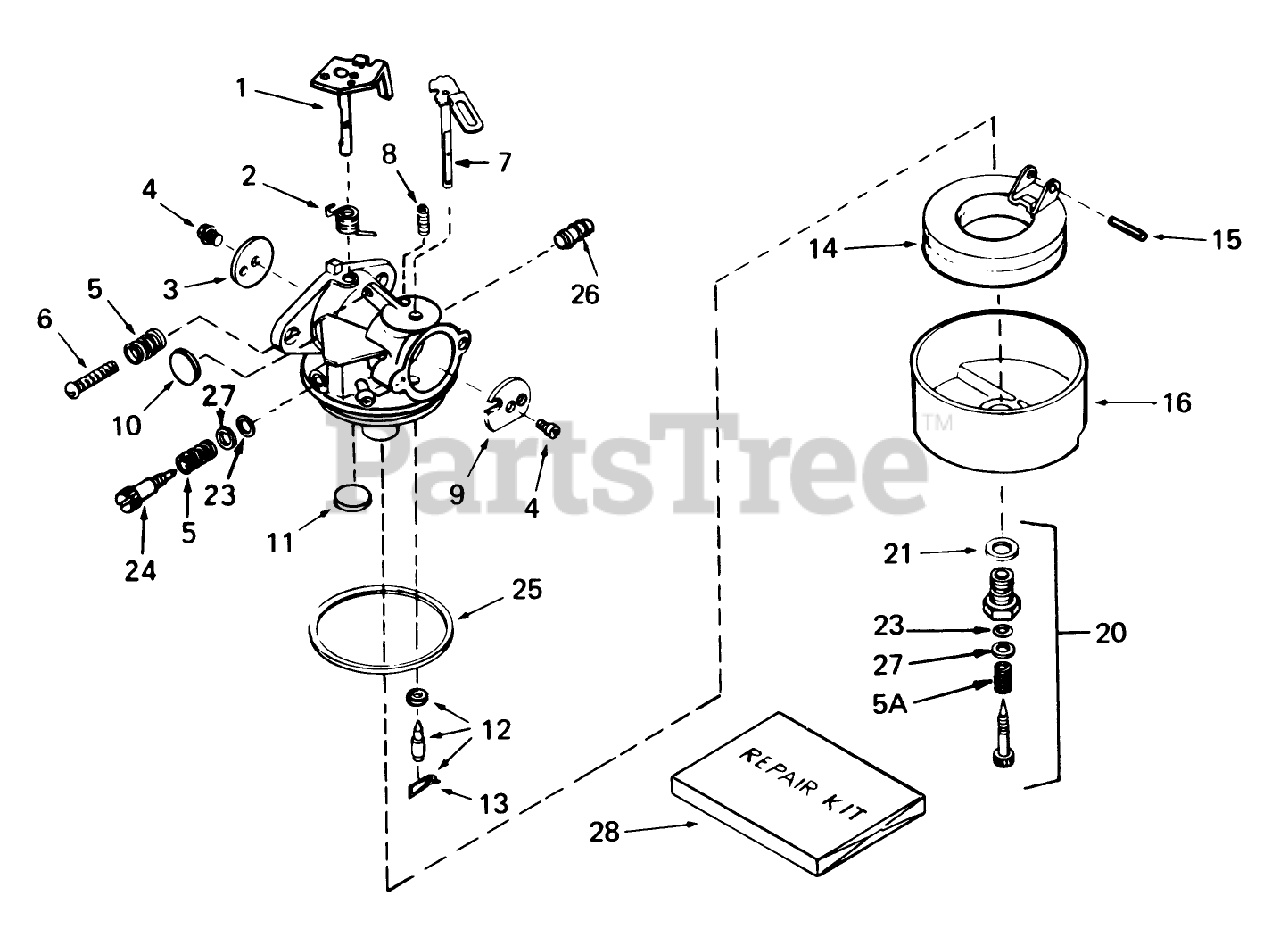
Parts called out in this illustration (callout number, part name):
1	Shaft/Lever-Throttle
2	Spring-Return, Throttle
3	Shutter-Throttle
4	Screw-Shutter
5	Spring-Tension
5A	Spring
6	Screw-Throttle Crack Screw / Idle Speed
7	Choke Shaft and Lever ASM
8	Spring-Positioning, Choke
9	Shutter, Choke
10	Plug-Welch, Idle Mixture Well
11	Plug-Welch, Atmospheric Vent
12	Inlet Needle, Seat Clip Assy. (Incl. No. 13)
13	Clip-Spring
14	Float
15	Shaft-Float
16	Bowl-Float (no drain)
20	Adjustment Screw Assembly, Main (Incl. Nos. 5A, 21, 23 27)
21	Washer-Bowl Nut
23	ORing
24	Screw Main Adjustment
25	O Ring-Bowl, Float
26	Fuel Fitting
27	Washer
28	Repair Kit
